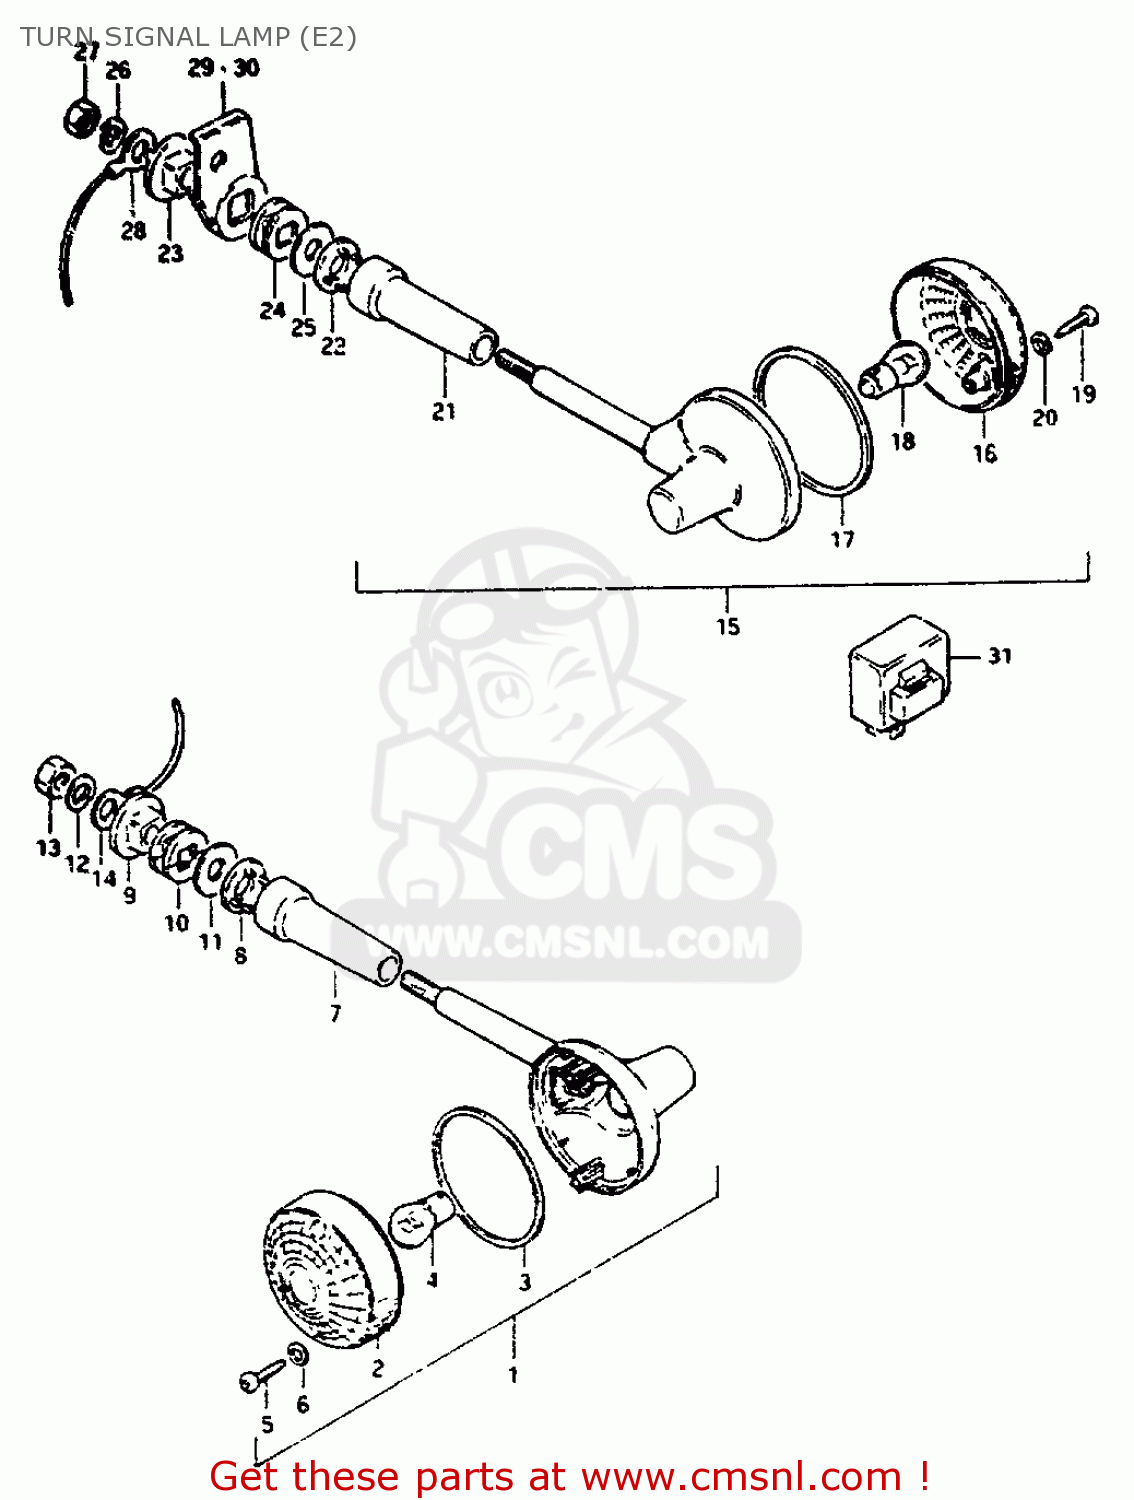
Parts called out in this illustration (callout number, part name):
1	LAMP, FRONT TURN SIGNAL
2	LENS
3	GASKET (NAS)
4	BULB 12V 21W
5	SCREW
6	GASKET (NAS)
7	COVER,STAY
8	SPACER
9	SPACER
10	CUSHION
11	WASHER (10.5X30X2.3)
12	LOCK WASHER
13	NUT
14	WIRE
15	LAMP, REAR TURN SIGNAL
16	LENS
17	GASKET (NAS)
18	BULB 12V 21W
19	SCREW
20	GASKET (NAS)
21	COVER,STAY
22	SPACER
23	SPACER
24	CUSHION
25	WASHER (10.5X30X2.3)
26	LOCK WASHER
27	NUT
28	WIRE
29	BRACKET,REAR TURN SIGNAL
30	BRACKET,REAR TURN SIGNAL
31	RELAY,TURN SIGNAL
